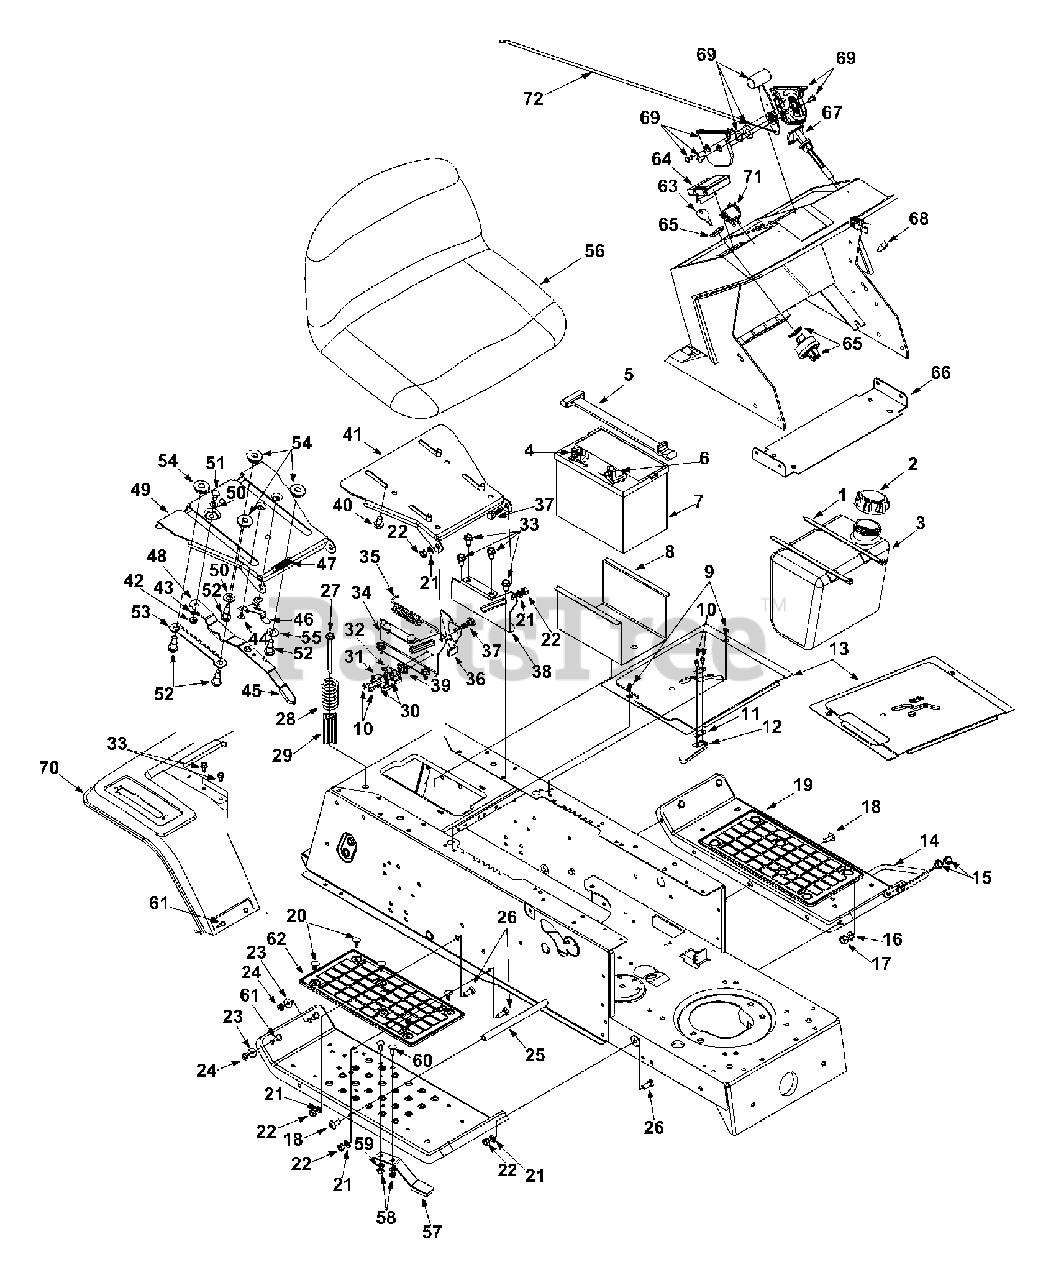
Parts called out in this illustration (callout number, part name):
1	Cable Tie
2	Fuel Cap
3	Fuel Tank 1.25 Gal.
3	Fuel Tank 1.50 Gal.
3	Fuel Tank 3 Gal.
4	Sems Hex Nut 1/4-20 Thd.
5	Battery Strap
6	Hex Hd. Cap Screw 1/4-20 Gr. 5
7	Battery
9	Truss Mach. B-Tap Scr. #10 x .5" Lg.
10	Hex AB-Tap Scr. #8 x .50" Lg.
11	Insulatop Nut Plate
12	Reverse Safety Switch
15	TT-Tap Scr. 5/16-18 x .625" Lg.
16	L-Wash. 3/8
17	Hex Nut 3/8-16 Thd. Gr. 8
18	Truss Mach. Scr. 5/16-18 x .75"
21	L-Wash. 5/16" I.D.
22	Hex Nut 5/16-18 Thd.
23	Bell-Wash. .265" I.D. x .75" O.D.
24	Hex Nut 1/4-20
25	Running Board Rod
26	Hex Bolt 5/16-18 x .75" Lg.
27	Hex Tap Scr. 5/16-18 x 3.25" Lg.
28	Compression Spring
29	Spring Spacer
30	Insulator Plate
31	Outer Spring Switch Spring
32	Inner Spring Switch Spring
33	Hex Wash. AB Scr. 5/16-12 x .75"
35	Extension Spring
36	Seat Lift Brkt.
37	Shoulder Bolt .437" Dia. x .268"
39	Insulator Boss Plate
40	Hex Tap Scr. 3/8-16 x .62" Lg.
42	Hex Flanged L-Nut 1/4-20 Thd.
43	Spring Wash. .265 I.D. x .562 O.D.
44	Hex Wash. Hd. B-Tap Scr.
45	Seat Adj. Grip
46	Seat Adj. Stop
47	Compression Spring
48	Seat Adj. Lever
51	Shoulder Bolt .34" x 1/4-20 Thd.
52	Shoulder Scr. 3/8-16
53	Seat Adj. Selector
54	Seat Adj. Spacer
55	Fl-Wash. .344 I.D. x .62 O.D.
56	Low Back Black Seat
56	Med. Back Black Seat
56	High Back Black Seat
56	High Back Black w/Drain Holes
57	Blade Brake Assembly
58	Hex Nut 1/4-20 Thd.
59	L-Wash. 1/4" I.D.
60	Carriage Bolt 1/4-20 x .62" Lg.
61	Hex Hd. Cap Scr. 1/4-20 x .62" Lg.
62	Rubber Foot Pad
63	Ignition Key
64	Ammeter
65	Ignition Switch - 5 Pin
65	Ignition Switch - 6 Pin
67	Choke Control 23"
67	Choke Control 29"
67	Choke Control 38"
67	Choke Control 46"
68	Choke Retainer
69	Throttle Box Ass'y
72	Throttle Control Wire 18.5"
72	Throttle Control Wire 22"
72	Throttle Control Wire 28"
72	Throttle Control Wire 35"
